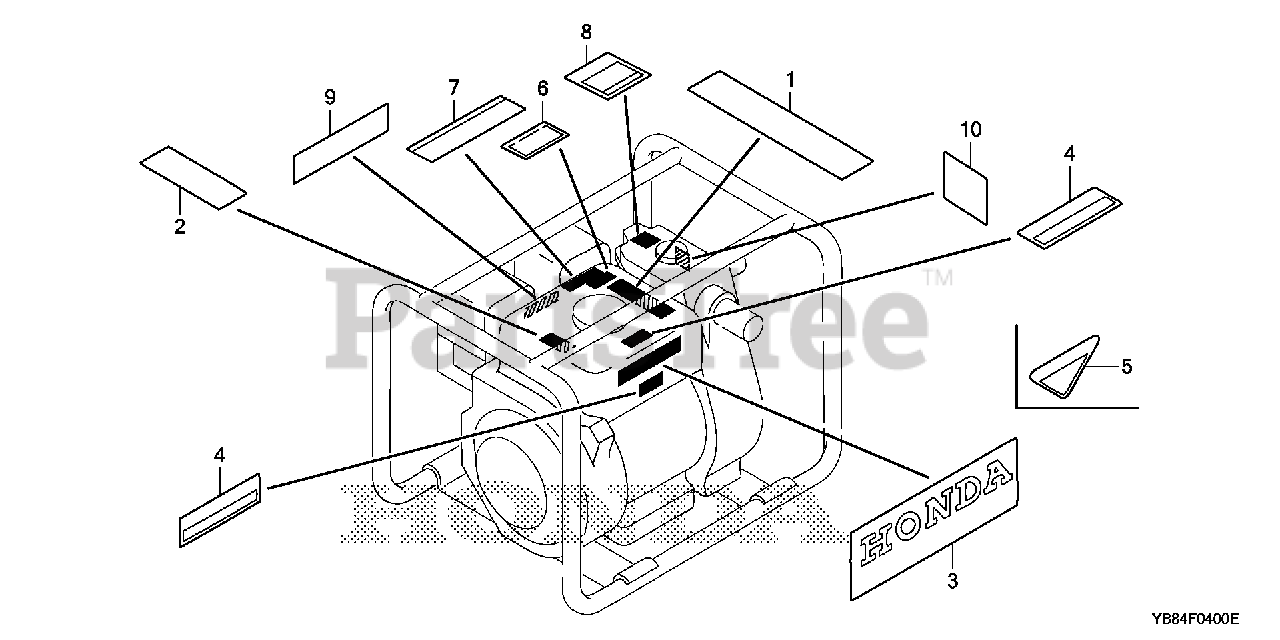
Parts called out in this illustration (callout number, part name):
1	MARK, CAUTION (PUMP)
2	LABEL, PUMP WARNING
3	MARK (WT30X)
